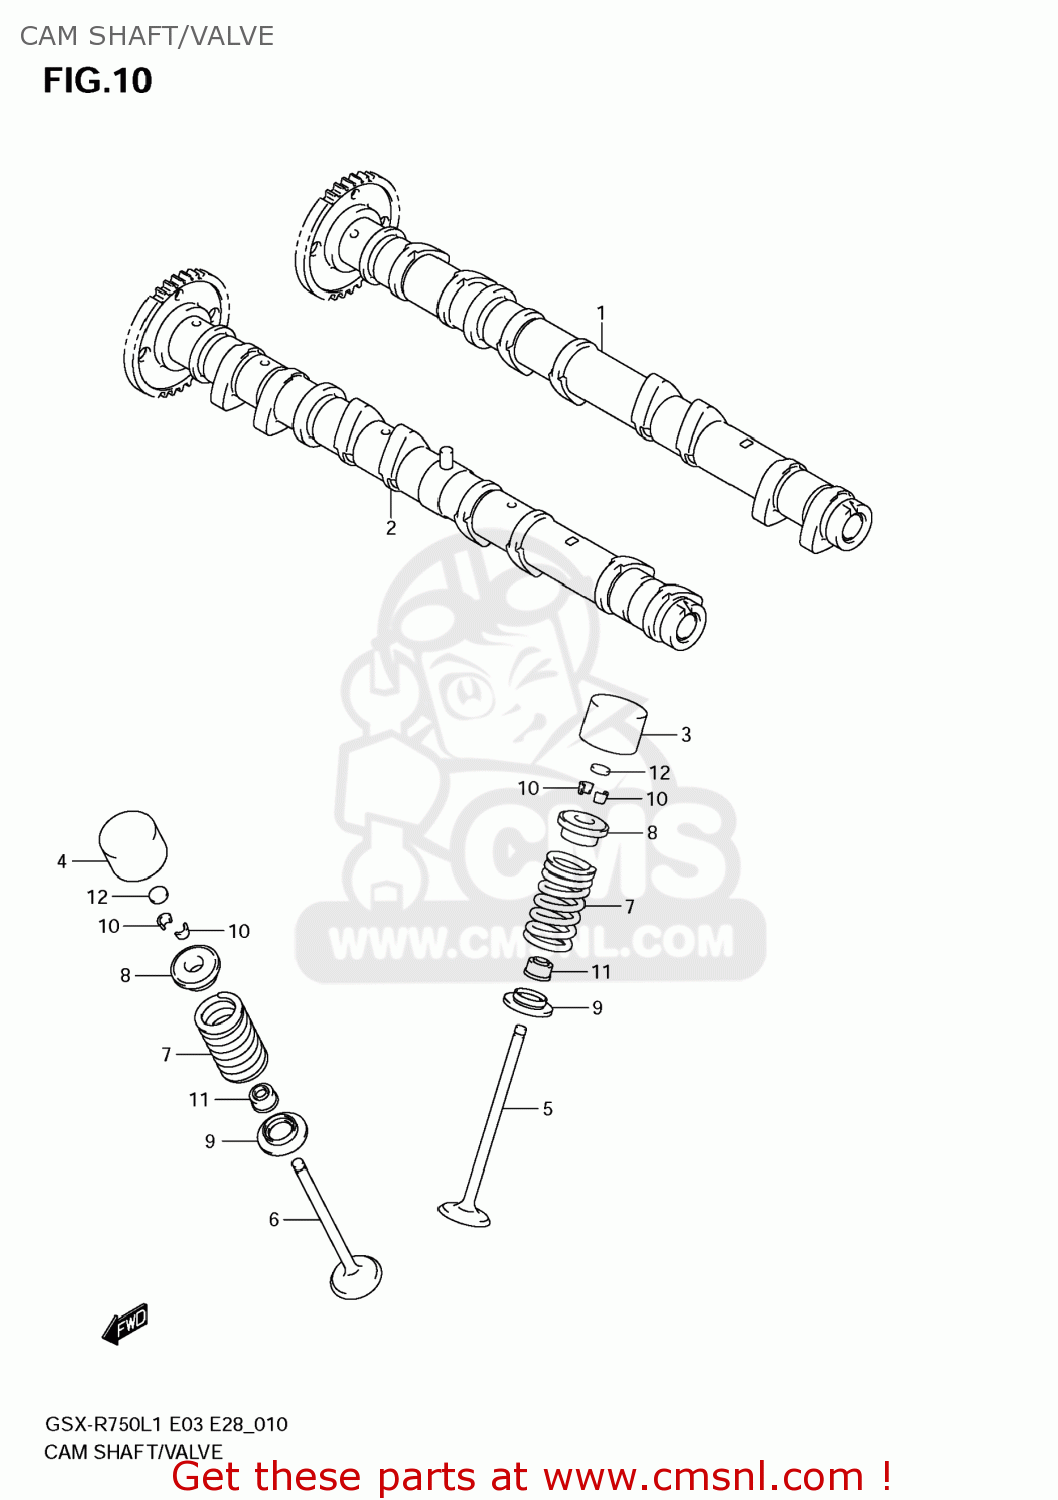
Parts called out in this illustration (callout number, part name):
1	CAMSHAFT,INTAKE
2	CAMSHAFT,EXHAUST
3	TAPPET
4	TAPPET,EXHAUST
5	VALVE,INTAKE
6	VALVE,EXHAUST
7	SPRING,VALVE
8	RETAINER,VALVE SPRING
9	SEAT,VALVE SPRING
10	COTTER VALVE
11	SEAL,OIL(4.5X10X8)
12	SHIM,TAPPET
13	SHIM SET,TAPPET
14	CASE,TAPPET SHIM
